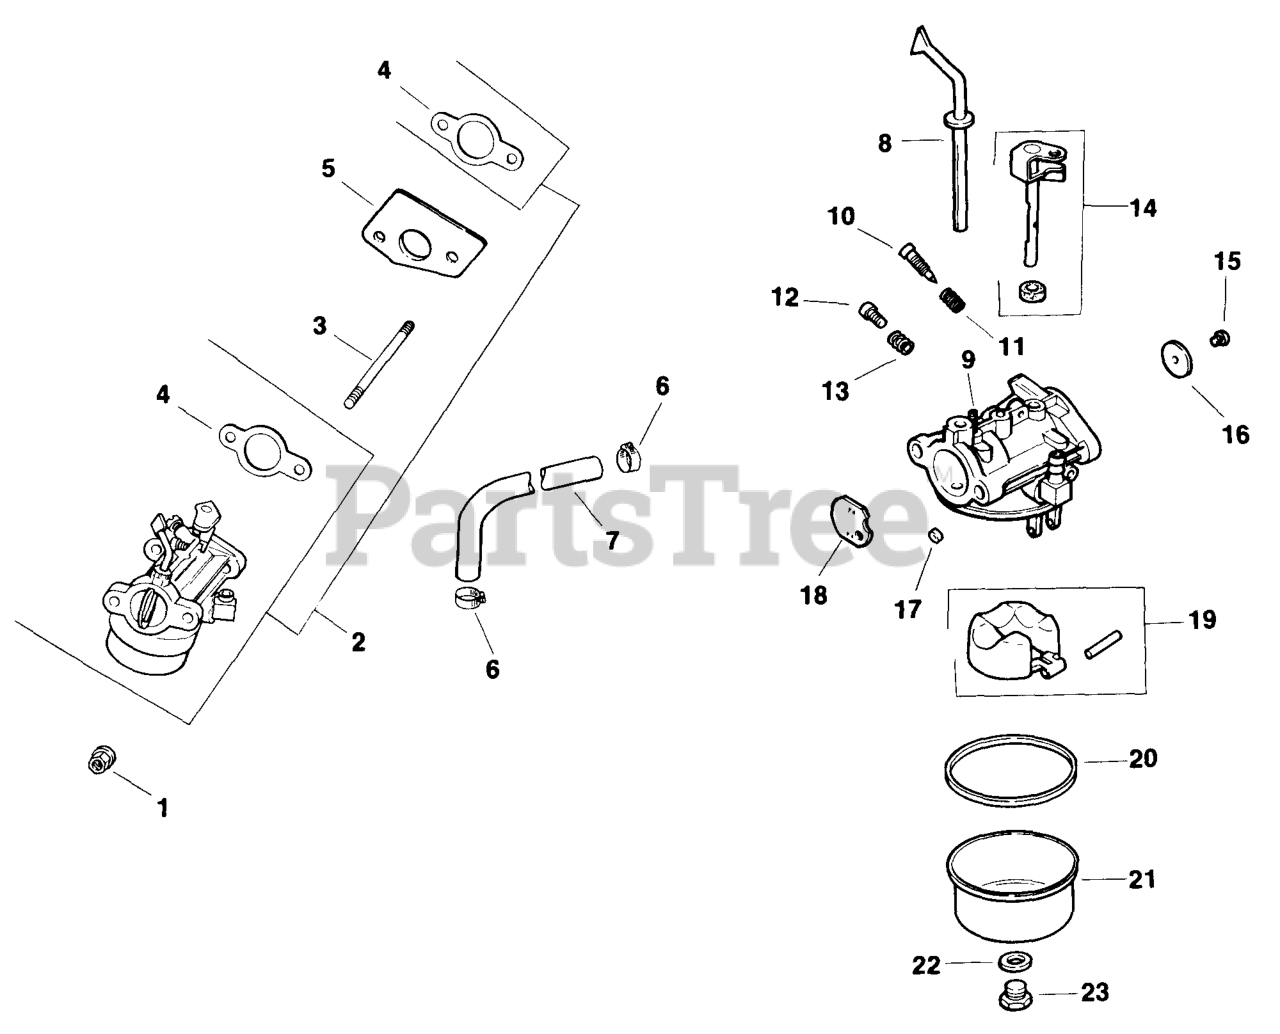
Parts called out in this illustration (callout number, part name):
1	Nut, hex. flange M6x1
3	Stud, carburetor mounting M6x1x91.9
4	GASKET, CARBURETOR
6	CLAMP, HOSE 1/2" USE 25 237 14-S
8	SHAFT, ASSEMBLY CHOKE
9	SPRING - DISCONTINUED
10	NEEDLE - DISCONTINUED
14	SHAFT, THROTTLE W/LEVER
15	SCREW, VALVE
16	PLATE - (#DSC)
17	JET, MAIN (.034) - DISCONTINUED
18	PLATE - DISCONTINUED
19	KIT, REPAIR FLOAT
20	GASKET, FUEL BOWL
23	SCREW, FUEL BOWL RETAINER
